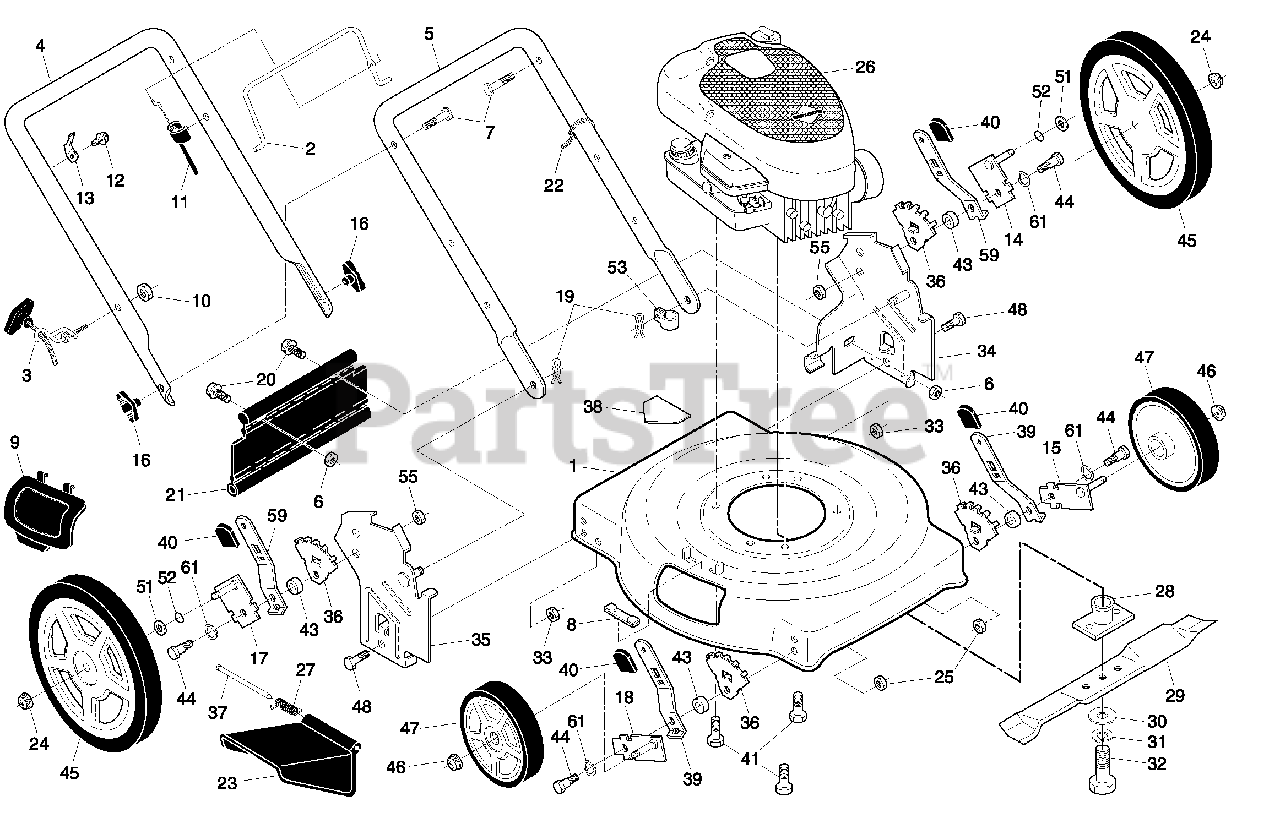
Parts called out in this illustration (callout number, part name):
1	Lawn Mower Housing
2	Control Bar
3	Rope Guide
4	Upper Handle
5	Lower Handle
6	Locknut, Hex 1/4-20
7	Handle Bolt 5/16-18
8	Clip, Closeout
9	Mulcher Plate
10	Nut, Hex 1/4-20
11	Engine Zone Control Cable
12	Hex Washer Head Screw #10-24 x 1/2
13	Up-Stop Bracket
14	Axle Arm Assembly, Rear, LH
15	Axle Arm Assembly, Front, LH
16	Handle Knob
17	Axle Arm Assembly, Rear, RH
18	Axle Arm Assembly, Front, RH
19	Hairpin Cotter
20	Screw, Hex Cap Head 1/4-20
21	Rear Deflector
22	Wire Tie
23	Discharge Guard
24	Nut, Hex, Flangelock 3/8-16
25	Nut, Hex, Flangelock 5/16-18
27	Torsion Spring
28	Blade Adapter
29	22" Blade
30	Hardened Washer
31	Helical Lockwasher 3/8
32	Screw, Hex Head, Grade 8, 3/8-24 x 1-3/8
33	Nut, Hex, Nylock 5/16-18
34	Wheel Bracket Support, LH
35	Wheel Bracket Support, RH
36	Wheel Bracket Adjuster
37	Hinge Rod
38	Danger Decal
39	Selector Spring, Front
40	Selector Knob
41	Screw, Hex Head, Threaded, Rolled 3/8-16 x 1
43	Spacer
44	Shoulder Bolt 5/16-18
45	Wheel & Tire Assembly, Rear, 12"
46	Nut, Hex, Flangelock 3/8-16
47	Wheel & Tire Assembly, Front, 7"
48	Bolt, Hex Head 5/16-18
51	Washer, Flat 3/8
52	O-Ring
53	Clip, Cable
55	Nut, Hex
59	Selector Spring, Rear
61	Washer, Curved, Cylindrical
61	Operator's Manual, English
61	Operator's Manual, French
61	Repair Parts Manual
